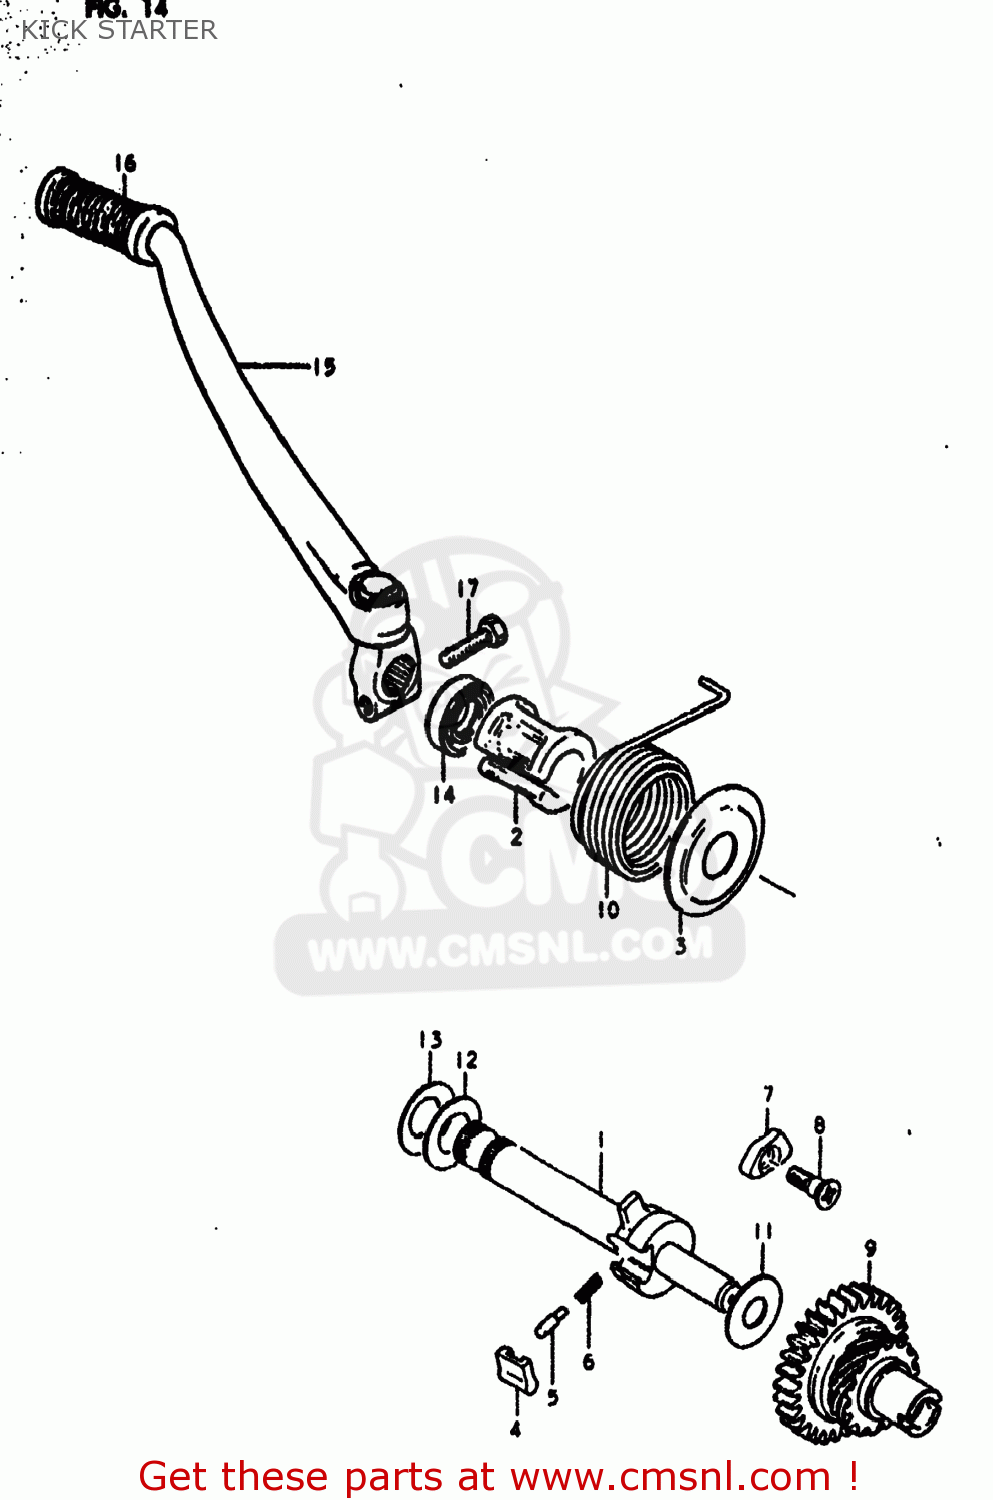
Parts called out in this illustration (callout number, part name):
1	SHAFT,KICK STARTER
2	GUIDE,KICK STARTER SFT SPRING
3	HOLDER,KICK STARTER SHAFT SPR
4	PAWL,KICK STARTER
5	PIN(5X15.5)
6	SPRING
7	LIFTER,KICK STARTER PAWL
8	SCREW(6X19)
9	GEAR,KICK STARTER DRIIVE
10	SPRING
11	WASHER(12X30X3)
12	WASHER(16X30X0.5)
13	WASHER
14	SEAL,OIL(16X30X8)
15	LEVER ASSEMBLY,KICK STARTER
16	RUBBER,KICK STARTER PEDAL
17	BOLT
